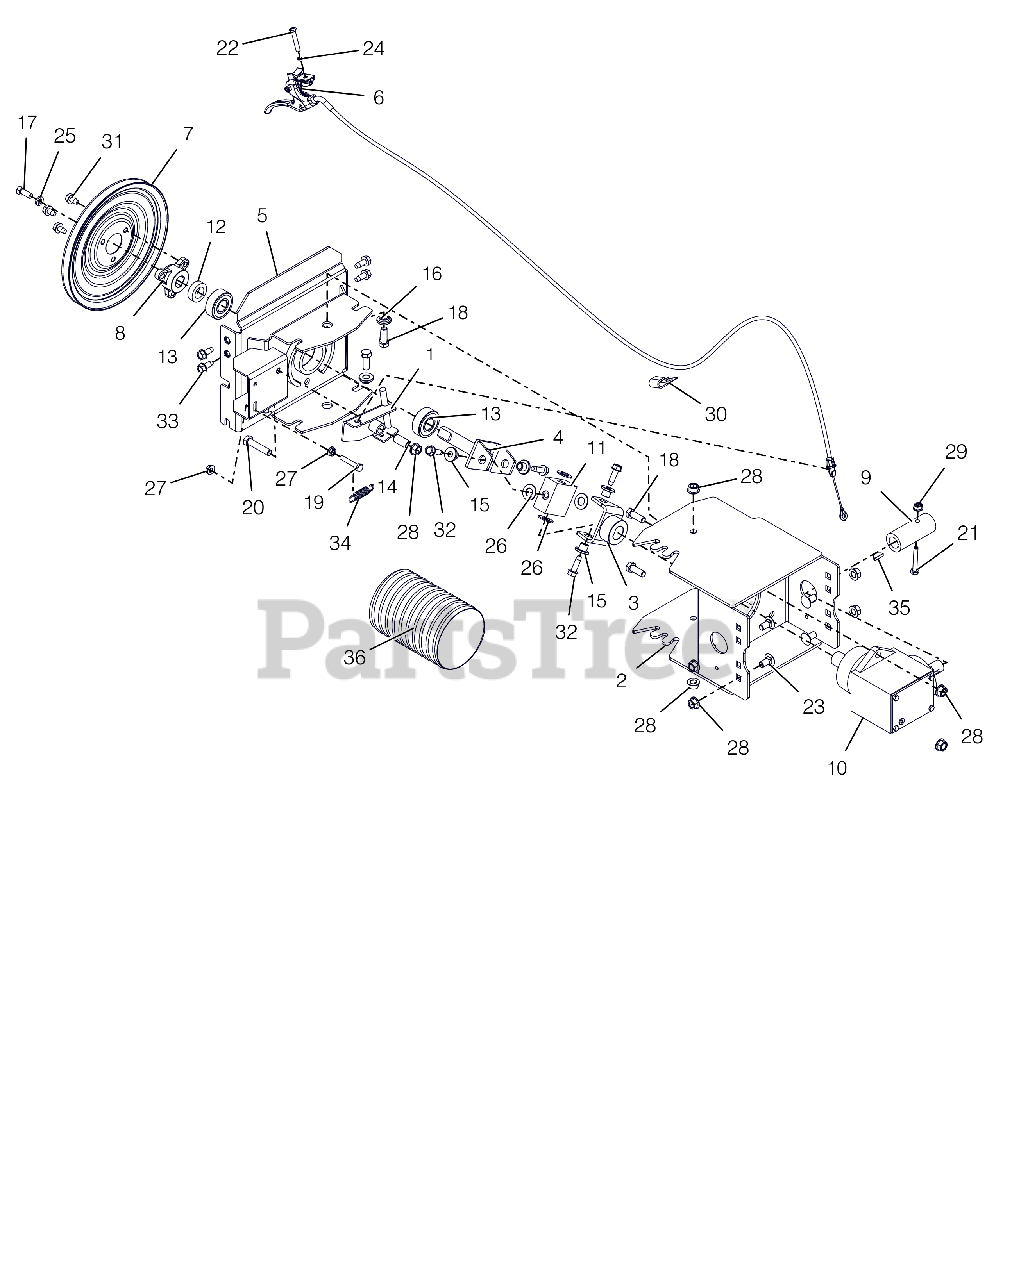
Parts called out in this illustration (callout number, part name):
1	ARM, PIVOT LOCK
2	ADAPTER, BROOM FRAME
3	JOINT,UNIVERSAL
4	JOINT,UNIVERSAL
5	ADAPTER, FRAME-20000 SERIES
6	CABLE, REMOTE BRUSH LOCK
7	PULLEY,SPIN FORM SINGLE GROOVE
8	PULLEY HUB, BOLT-ON D-BORE .75
9	HUB, COUPLING
10	GEAR BOX ASSEMBLY
11	BLOCK, UNIVERSAL
12	SPACER .755X1.250X.370
13	BRG-BALL .750X1.781X.61
14	BSHG-SLV .385X.500X1.045
15	BSHG-FLG .325X.500X.513X.875
16	BSHG-FLG .406X.88X.270X.140
17	BLT-HEX .31-24X.75 YWZC GR5
18	@BLT-HEX .38-16X1.00 GR5 YWZC
19	@BLT-HEX .25-20X1.50 GR5 YWZC
20	@BLT-HEX .38-16X1.75 GR5 YWZC
21	@BLT-HEX .25-20X1.75 GR5 YWZC
22	SCR-MCH .25-20X1.50 OVAL HD
23	@BLT-RDHDSQNK .38-16X.75 G5YZ
24	WSHR-LK-INT .250 TH TYA
25	WSHR-LK .312X.097 HVY YWZC
26	WSHR-HDND-STL-THR.515X.97X.062
27	@NUT-SPNLK-FLG .25-20 YWZC
28	@NUT-LK-TOP-FLG .38-16 YWZC
29	@NUT-LK-TOP-FLG .25-20 YWZC
30	J-CLAMP
31	@SCR-TAP .31-18X.50 HWH TR YWZ
32	@SCR-TAP .31-18X1.00 HWH TR YZ
33	@SCR-TAP .31-18X.75 HWH TR YWZ
34	SG-TENS .06X.46X2.00
35	KEY-WDRF .188X.75X.313 SAE 9
36	HOSE 4" X 7" FLEX TUBE PV
